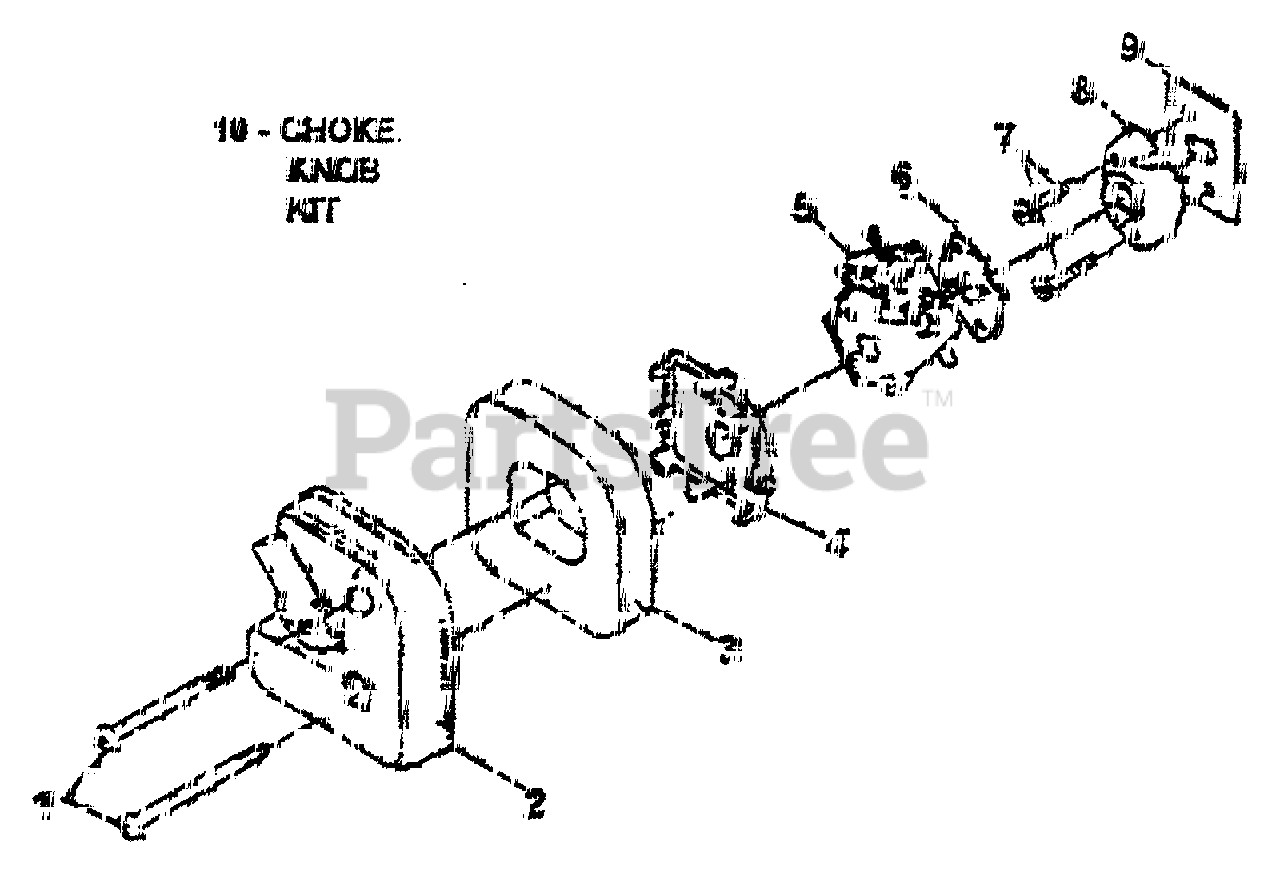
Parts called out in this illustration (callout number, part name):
1	SCREW, CHOKE COVER
2	COVER ASSY, AIR/CHOKE
3	AIR FILTER
5	CARBURETOR
6	GASKET CARB/INS.
7	SCREW
8	INSULATOR
9	GASKET, INS./CYL.
10	CHOKE KNOB KIT
